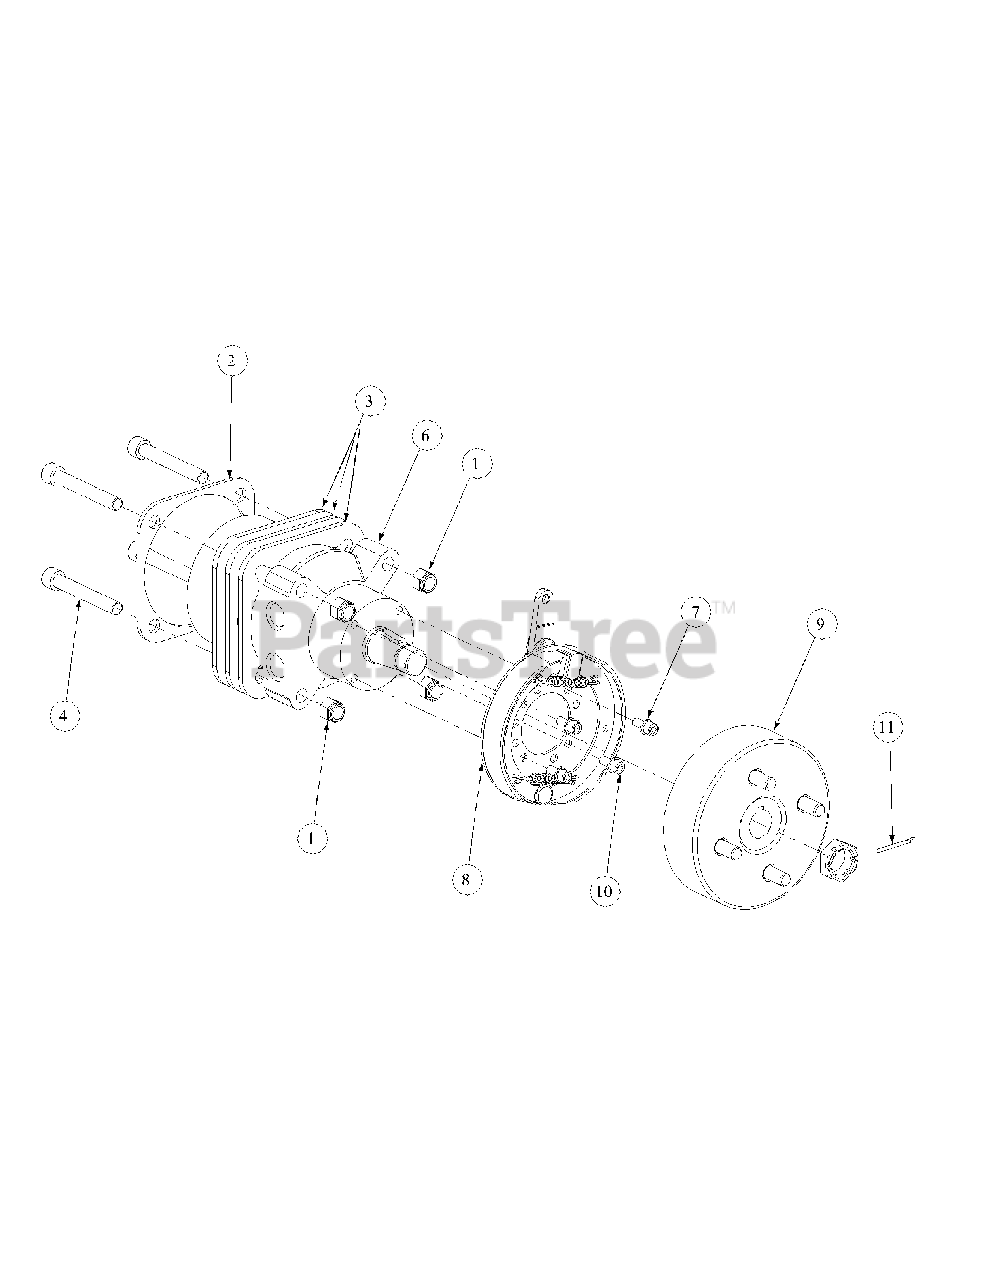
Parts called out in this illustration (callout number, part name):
1	Lock Nut, Nylon Insert, 1/2-13
2	Motor Plate
3	Motor Spacer
4	Socket Head Capscrew, 1/2-13; 3-1/2
4	Capscrew, 1/2-13 x 3.5
5	Hyd. Motor, Parker Left Hand
6	Hydro Motor, Parker Right Hand
7	Lock Washer, 5/16
8	Brake Assembly w/Line
9	Hub and Drum Assembly w/Studs
10	Capscrew w/Socket, 5/16-18 x 3/4
11	Cotter Pin 1/8 x 1-1/2
